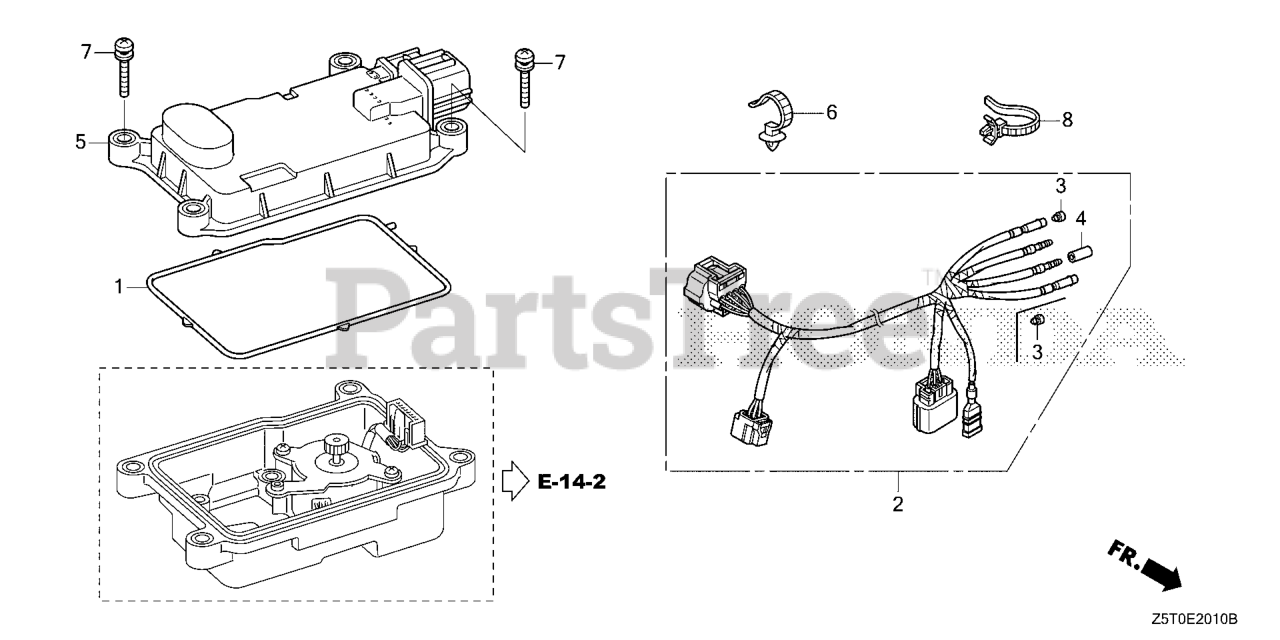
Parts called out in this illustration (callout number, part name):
1	SEAL, ELECTRONIC CONTROL UNIT COVER
2	WIRE HARNESS ASSY., ENGINE
3	PLUG, CONNECTOR (INNER) (TROLLING CONTROL)
4	PLUG, CONNECTOR (OUTER) (ENGINE NO.)
5	CONTROL UNIT, ELECTRONIC
7	SCREW-WASHER (4X20)
